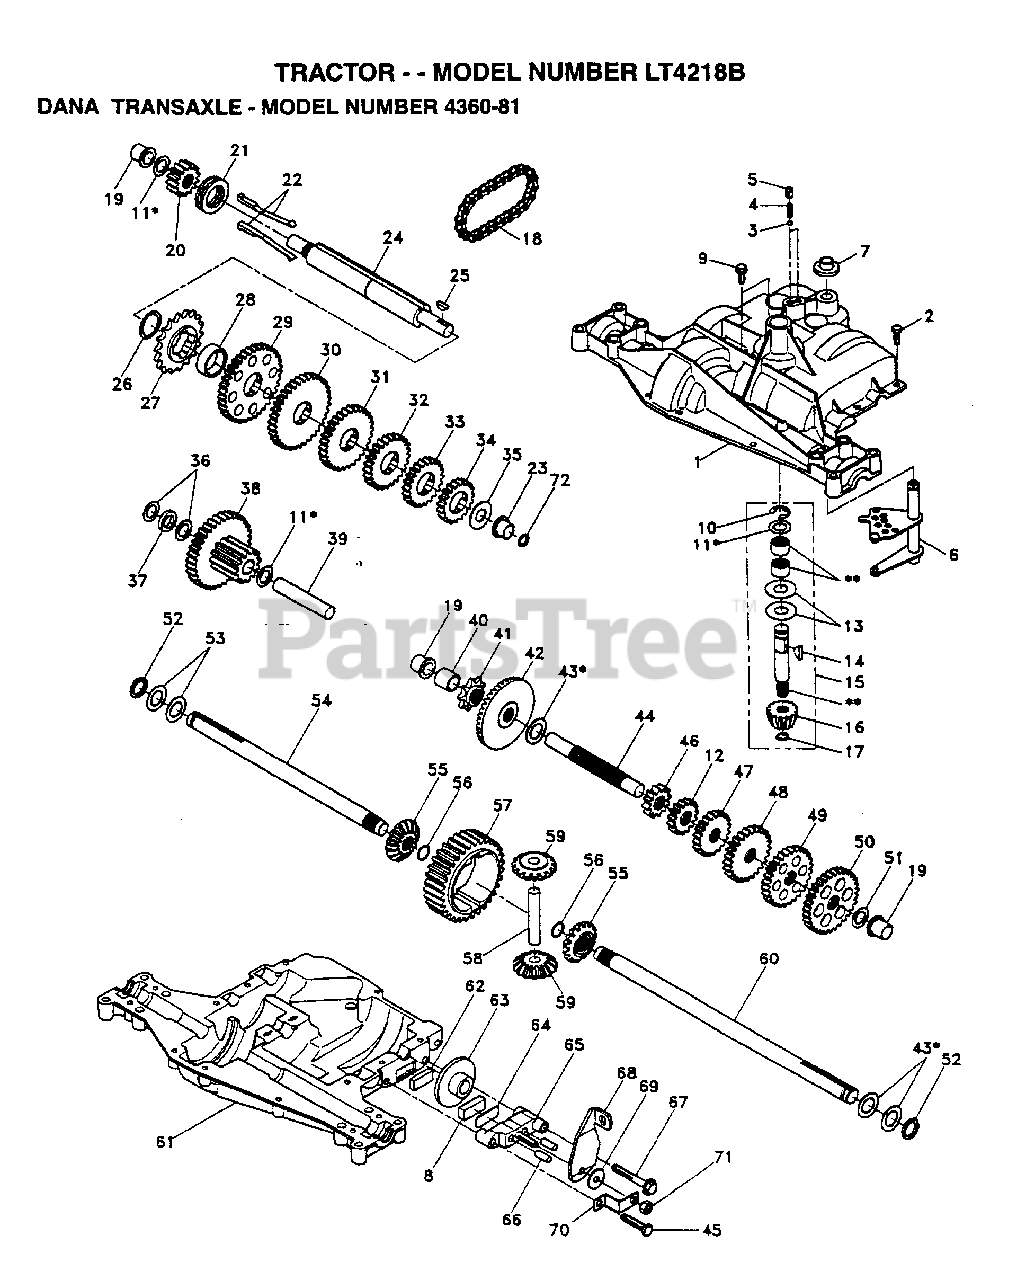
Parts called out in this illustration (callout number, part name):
1	HOUSING UPPER TRN
4	"SPRING, DETENT LT"
5	"SCREW, SET LT"
6	SHIFTER.ASM.KIT.
7	SHIFTER BOOT
8	PUCK T
9	SCREW TAP W/SEAL
11	ASM KIT SHIM 4689
12	GEAR SPUR 15 TTH
13	WASHER T
14	KEY WOODRUFF-DANA
17	"RING,RETAINING LT"
18	"CHAIN,24 PTCH LT"
19	BEARING.FLNG.5510
20	GEAR SPUR 14 TTH
21	COLLAR CLUTCH
22	KIT.ASM.CLUTCH KY
24	SHAFT INTERM DANA
25	WOODRUFF KEY
26	"RING,RETAINING LT"
27	SPROCKET 18T T
28	SPACER YT
29	GEAR SPUR 37 TTH
30	GEAR SPUR 35 TTH
32	GEAR 25T LT
33	GEAR SPUR 22 TT
34	SPUR GEAR 19T
35	"WASHER, PLAIN LT"
36	WASHER 025
37	SPACER
38	ASSM GEAR COMB
39	SHAFT IDLER
40	SPACER T
41	SPROCKET 9T LT
43	ASM KIT SHIM
44	SHAFT T
45	"SCREW, TAPPING LT"
46	GEAR SPUR 12 TTH
48	"GEAR, SPUR 25T LT"
49	GEAR 28T T
50	"GEAR, SPUR 31T LT"
51	WASHER 060
52	NEOPRENE WASHER
53	WASHER 031
55	GEAR LT
56	"RING,RETAINING LT"
58	SHAFT T
59	"GEAR,MITER 15T YT"
61	HOUSING LOWER TNS
62	PUCK T
63	BRAKE DISC. T
64	SPACER LT
66	PIN T
69	WASHER LT
71	NUT.LOCK.5/16-24
72	SEAL OIL DANA5416
